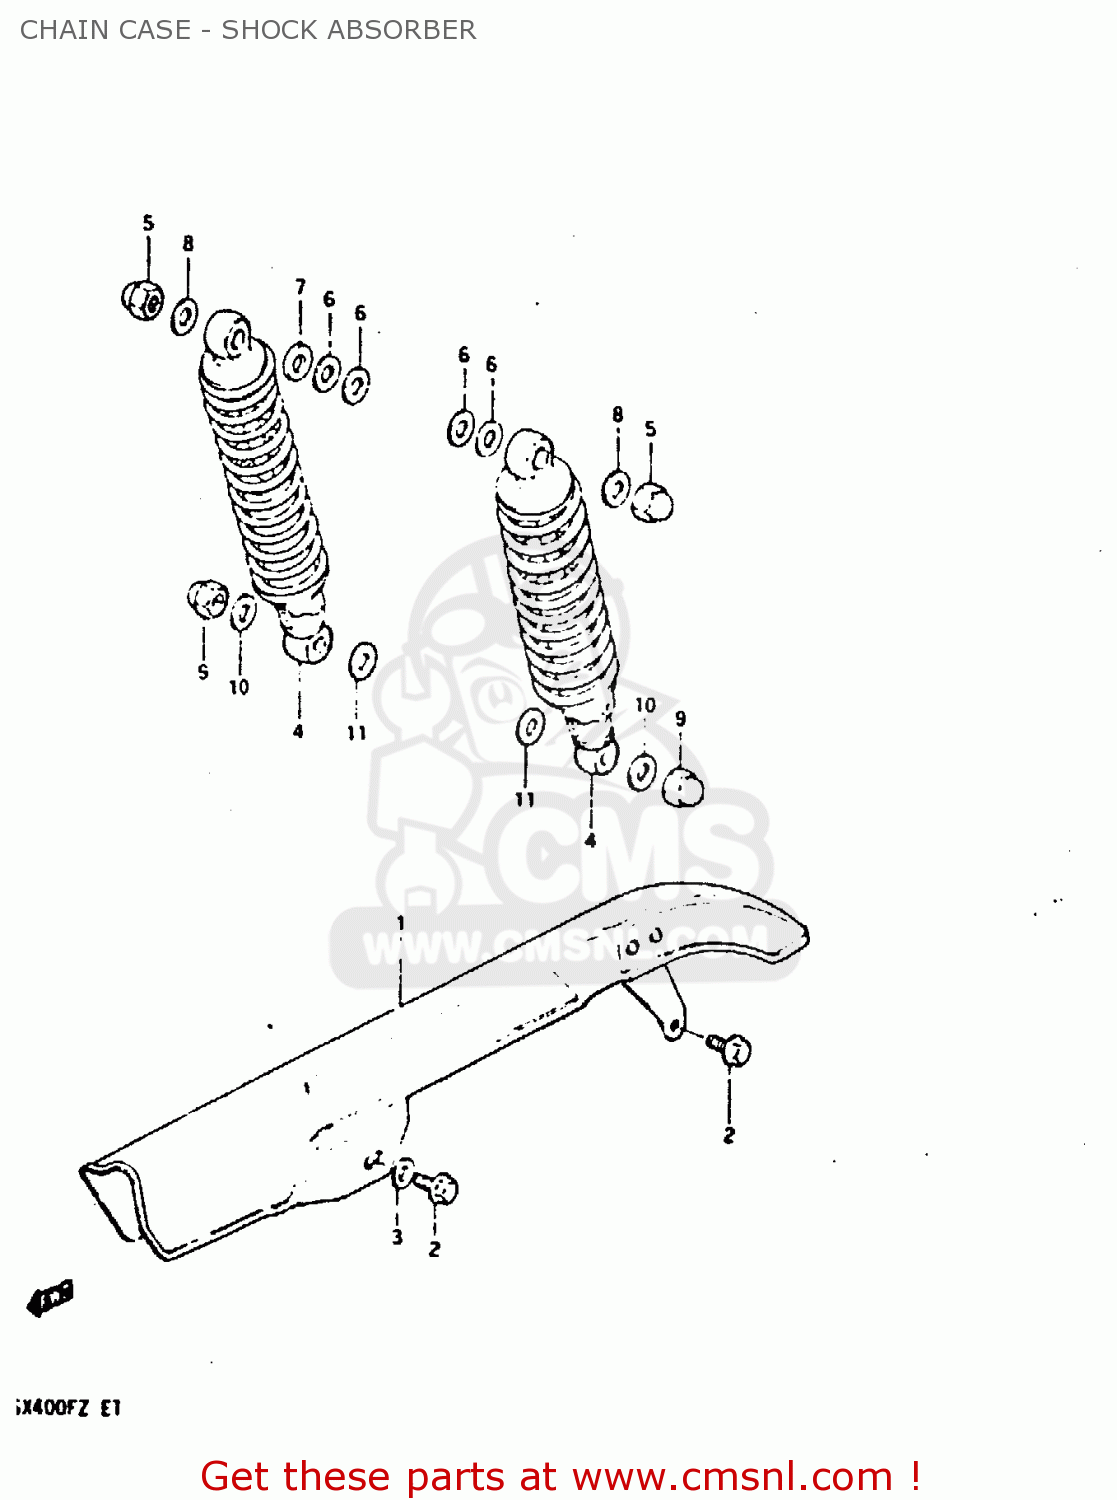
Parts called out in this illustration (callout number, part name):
1	CHAIN CASE
2	BOLT
3	WASHER
4	SHOCK ABSORBER, REAR
5	NUT
6	WASHER
7	WASHER (12.5X24X3.2)
8	WASHER
9	NUT, LOWER LH
10	WASHER
11	WASHER (12.5X24X1.6)
